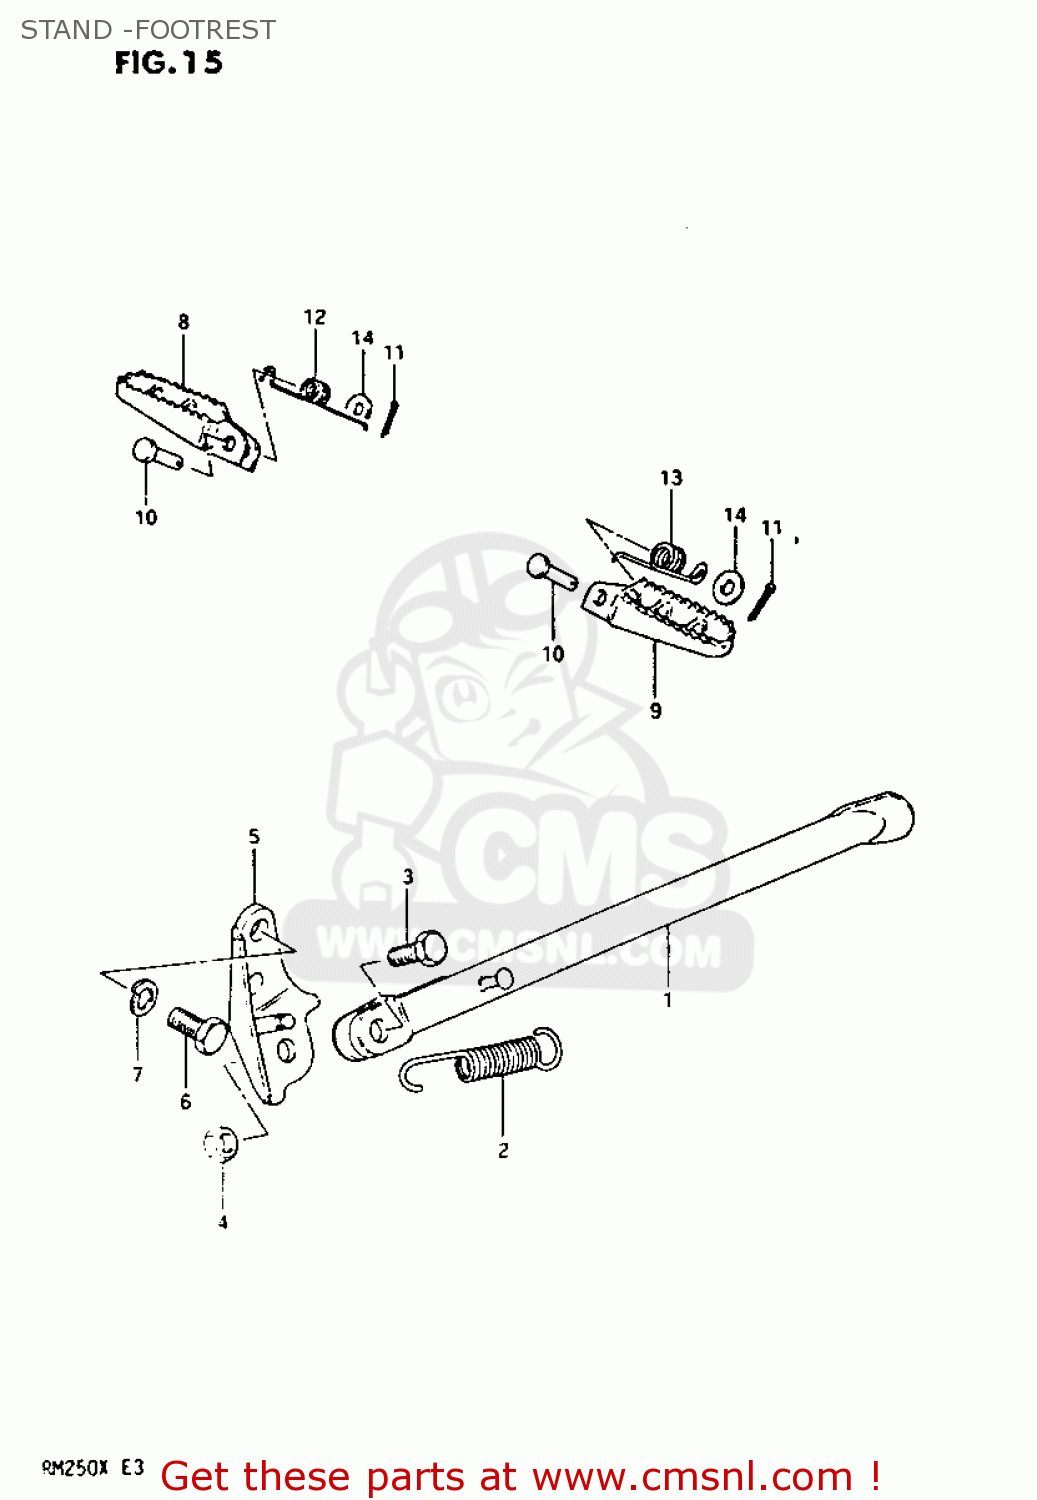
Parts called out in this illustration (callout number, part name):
1	STAND,SIDE
2	SPRING
3	BOLT(10X30)
4	NUT
5	BRACKET,SIDE STAND
6	BOLT(10X19)
7	WASHER,LOCK,10
8	FOOTREST,FR,R
9	FOOTREST,FR,L
10	PIN
11	PIN 20X20
12	SPRING
13	SPRING
14	WASHER
